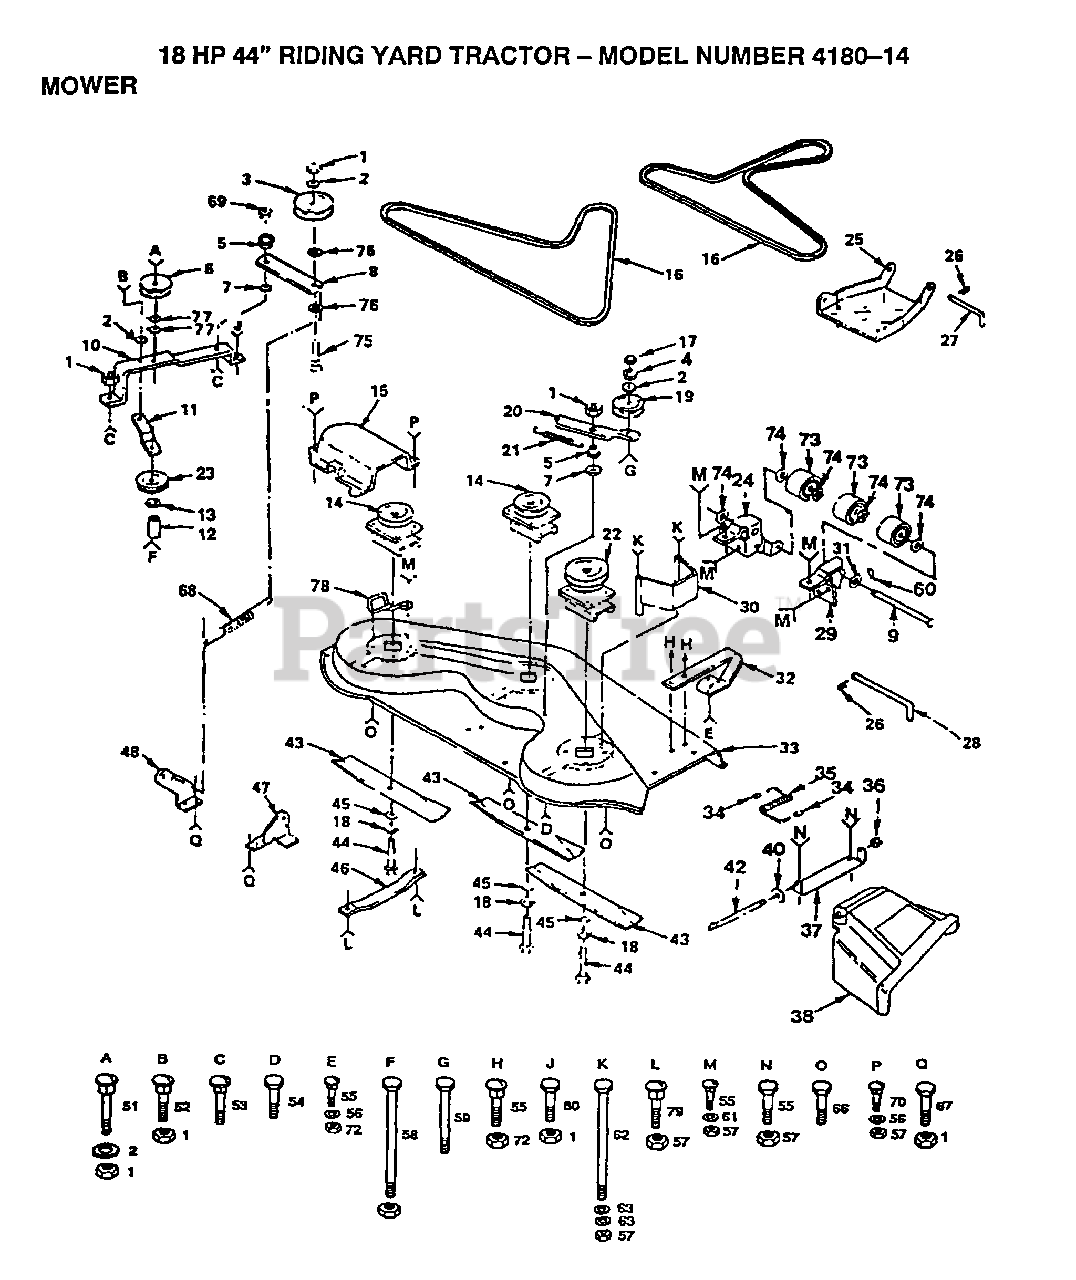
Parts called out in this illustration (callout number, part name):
2	WASHER
3	PULLEY IDLER
4	LOCKWASHER
5	SPACER RETAINER
6	IDLER-INSIDE T
7	"WASHER, WEAR LT"
8	ARM IDLER
9	PIVOT PIN T
10	"SUPPORT YT, BAR"
11	BRACE-IDLER YT
12	SPACER
13	WASHER
15	GUARD YT
16	BELT-V.79.1.MWR
17	NUT.HEX.3/8-16UNC
19	IDLER.FLAT.GTV
20	ARM-IDLER YT
22	JACKSHAFT
23	IDLER-FLAT T
24	BRACKET LH YTH
25	LINK.PARALLEL
26	SPRING.RETAINER
27	"ROD, FRT. PARAL T"
28	HINGE PIN T
29	BRACKET RH YTH
30	GUARD BELT HYT
34	CAP-SLEEVE LT
36	NUT PUSH M
38	DEFLECTOR SHIELD
40	WASHER
42	ROD-HINGE T
44	BOLT.3/8-24X1-1/2
45	WASHER
46	RUNNER-LH M
47	BRKT SUSP REAR RH
48	BRKT SUSP REAR LH
51	BOLT
53	BOLT
55	BOLT
56	WASHER
58	BOLT - HEX 3/8 - 16 X 3
59	SCREW YT
60	COTTER PIN
61	WASHER M
62	BOLT
63	WASHER M
66	SCREW
67	BOLT
68	"SPRING.EXT.8.5"""
69	LOCKNUT
73	ROLLER T
74	WASHER T
75	BOLT
76	WASHER
77	WASHER
78	BELT RETIANER
79	BOLT
80	BOLT
